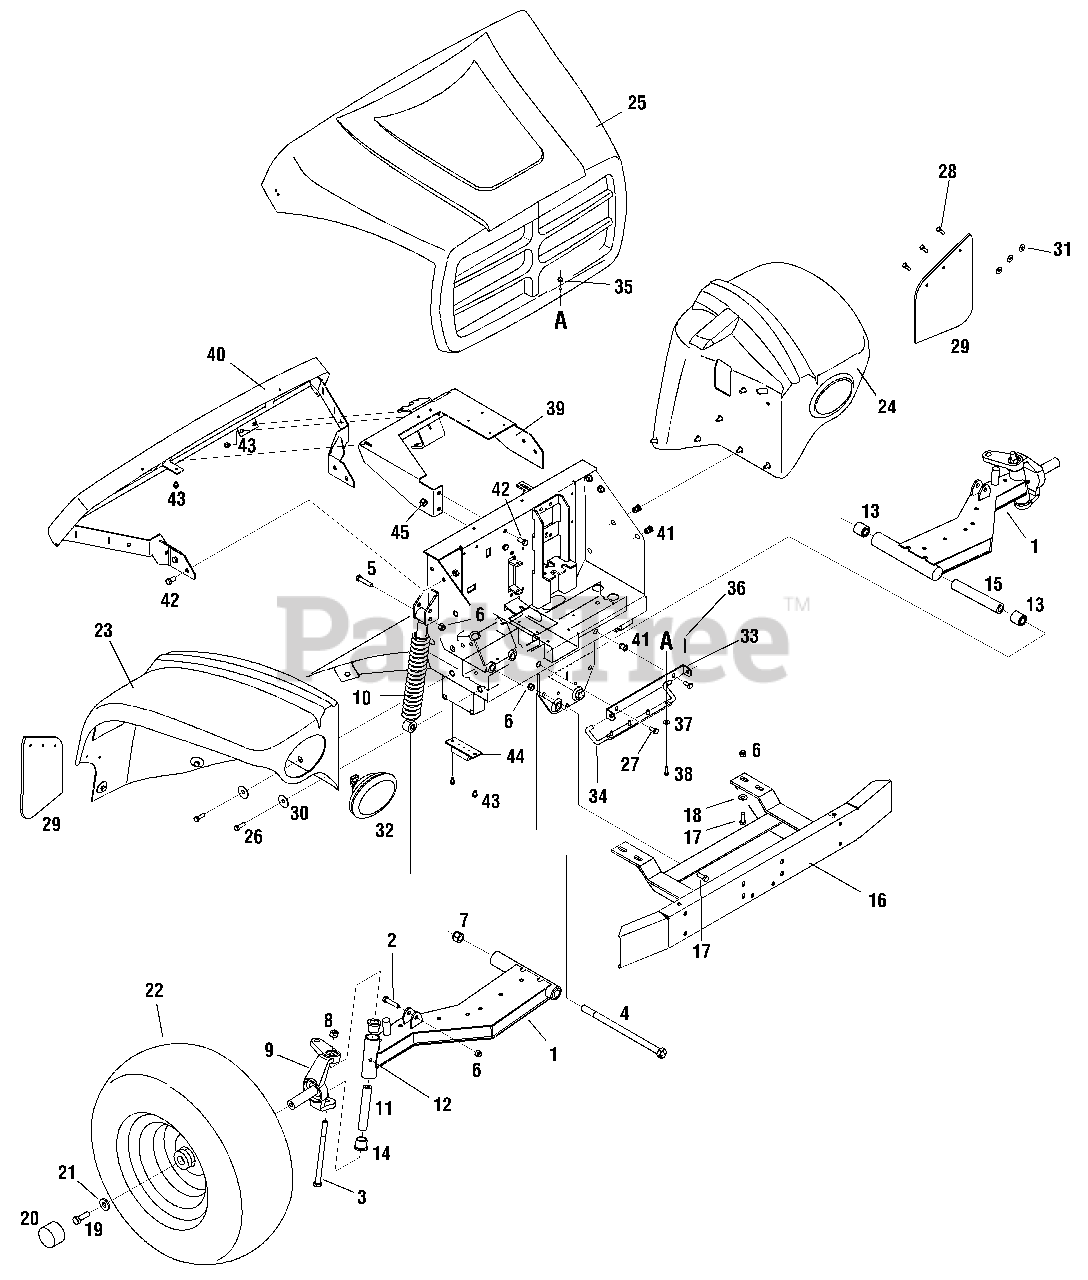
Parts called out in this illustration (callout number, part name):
1	Axle Assembly, Right-front
2	Hex Screw, 3/8-16 x 1.75
3	Hex Screw, 1/2-13 x 7.0, Gr5
4	Hex Screw, 5/8-11 x 11.13, Gr5
5	Hex Screw, 3/8-16 x 2.25
6	Nut, Hex Lock, Nylon, 3/8-16, Gr5
7	Nut, Hex Lock, Nylon, 5/8-11, Gr5
8	Nut, Hex Lock, 1/2-13
9	Steering Control Knuckle, RH
10	Shock Absorber, 2.9 Stroke
11	Tube, .875 x .50 x 4.75
12	Grease Fitting
13	Bearing, .63 ID x 1.19 OD
14	Bushing, Steering
15	Spacer, .645 ID x 1.063 OD
18	Flat Washer, .406 x .875 x .059
19	Hex Screw, 1/2-13 x 1.50, Gr5
21	Flat Washer, .531 x 1.25 x .181
22	Wheel Ass'y, 22.5 x 10 x 8, Knobby
23	Panel Assembly, Right Fender, Yellow
24	Panel Assembly, Left Fender, Yellow
25	Panel Assembly, Hood, Yellow
26	Hex Screw 5/16-18 x 1.00 Gr 5
27	Hex Screw, 5/16-18 x .75
28	Pop Rivet
30	Washer, Bell, .39 x 1.38 x .062
31	Flat Washer, .194 x .62 x .063
32	Head lamp Assembly
35	Nut, Hex Lock, 1/4-20
36	Cotter Pin, Internal, 1.42
37	Washer, Flat, .271 x .63 x .065
38	Hex Screw, 1/4-20 x .75
41	Insert Nut, 5/16-18
42	Hex Screw, 3/8-16 x .75
43	Screw, Self-tapping, 1/4-20 x .5
44	Suspension Bumper
45	Flange Lock Nut, 3/8-16
